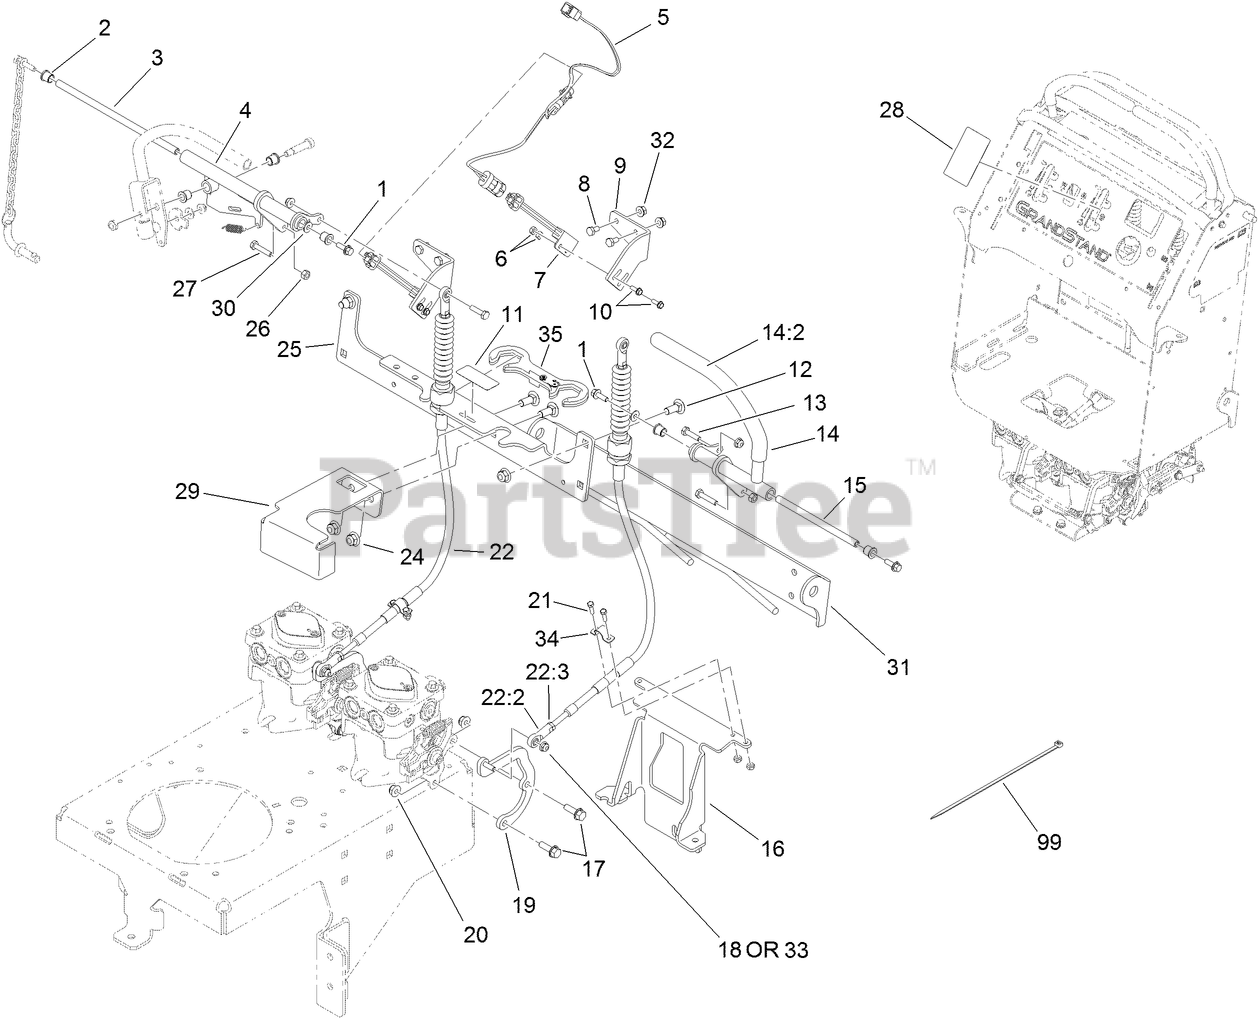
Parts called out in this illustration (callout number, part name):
1	SCREW-HHF
2	BEARING
3	SHAFT-PIVOT
4	RH MOTION CONTROL ASM
5	HARNESS-WIRE
6	NUT-LOCK, NI
7	SWITCH-PROXIMITY
8	SCREW-HH
9	BRACKET-MOUNT, SWITCH
11	DECAL-TRACKING, HYDRO
12	BOLT-CARR
13	SCREW-HH
14	LH LEVER ASM
15	SHAFT-PIVOT, MOTION CONTROL
16	BRACKET-MOUNT, CABLE
17	SCREW-HHF
18	NUT-HF
19	PUMP LEVER ASM
20	NUT-HF, NI
22	CABLE ASM
22:2	ROD END-BALL JOINT
22:3	NUT-JAM
24	NUT-HF, NI
25	BRACKET-CROSS
26	NUT-HEX
27	SCREW-HH
28	DECAL-COVER UP
29	BRACKET-TANK
30	WASHER-FLAT
31	HINGE-LOWER
32	NUT-HHF
33	NUT-LOCK, NI
35	LOCK-CABLE
99	TIE-PLASTIC
